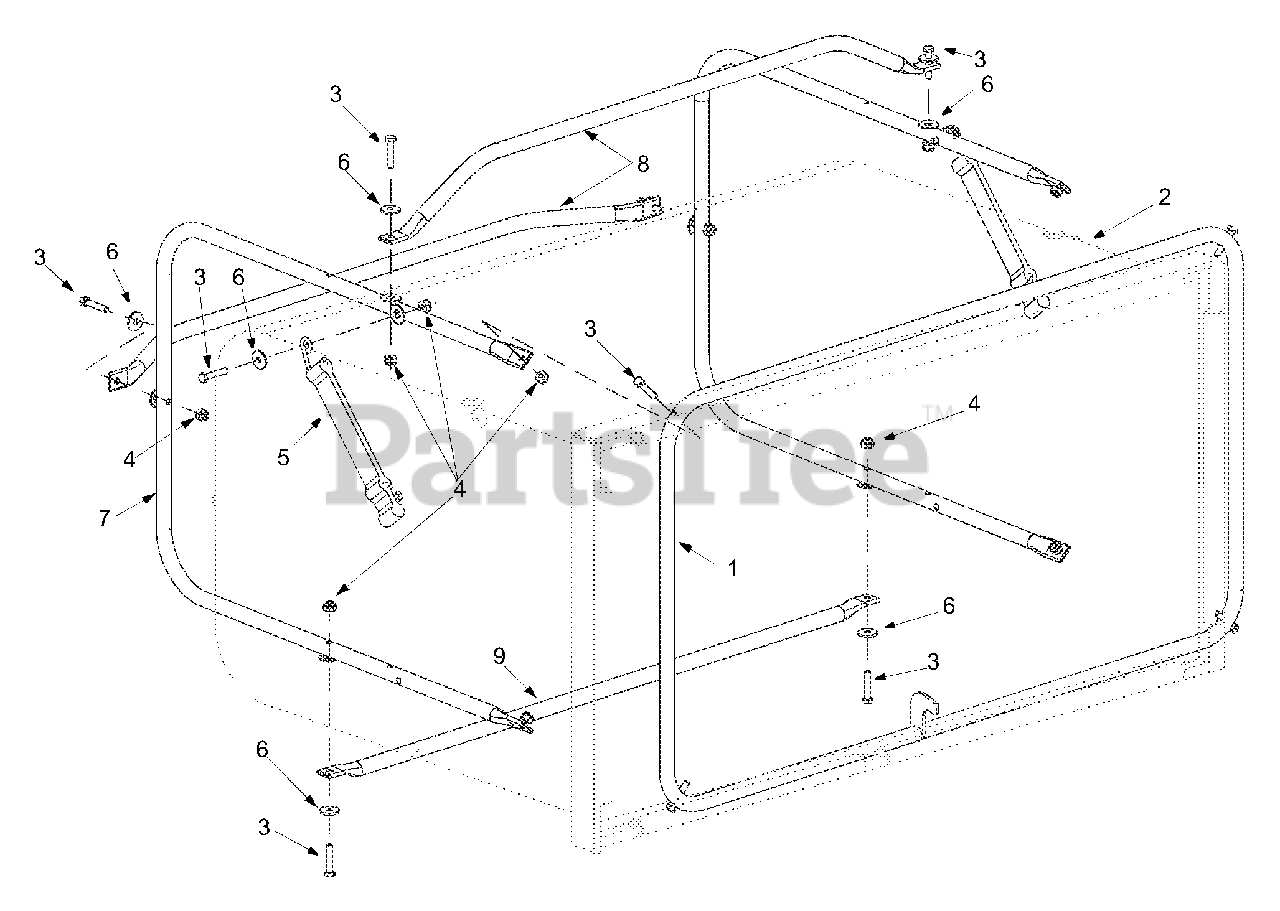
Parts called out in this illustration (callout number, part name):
3	Mach. Screw #10-24 x 1.0
4	Lock Nut #10-24
5	Retainer Strap
6	Flat Washer
7	Side Tube: Frame
8	Bag Handle
9	Support Tube
